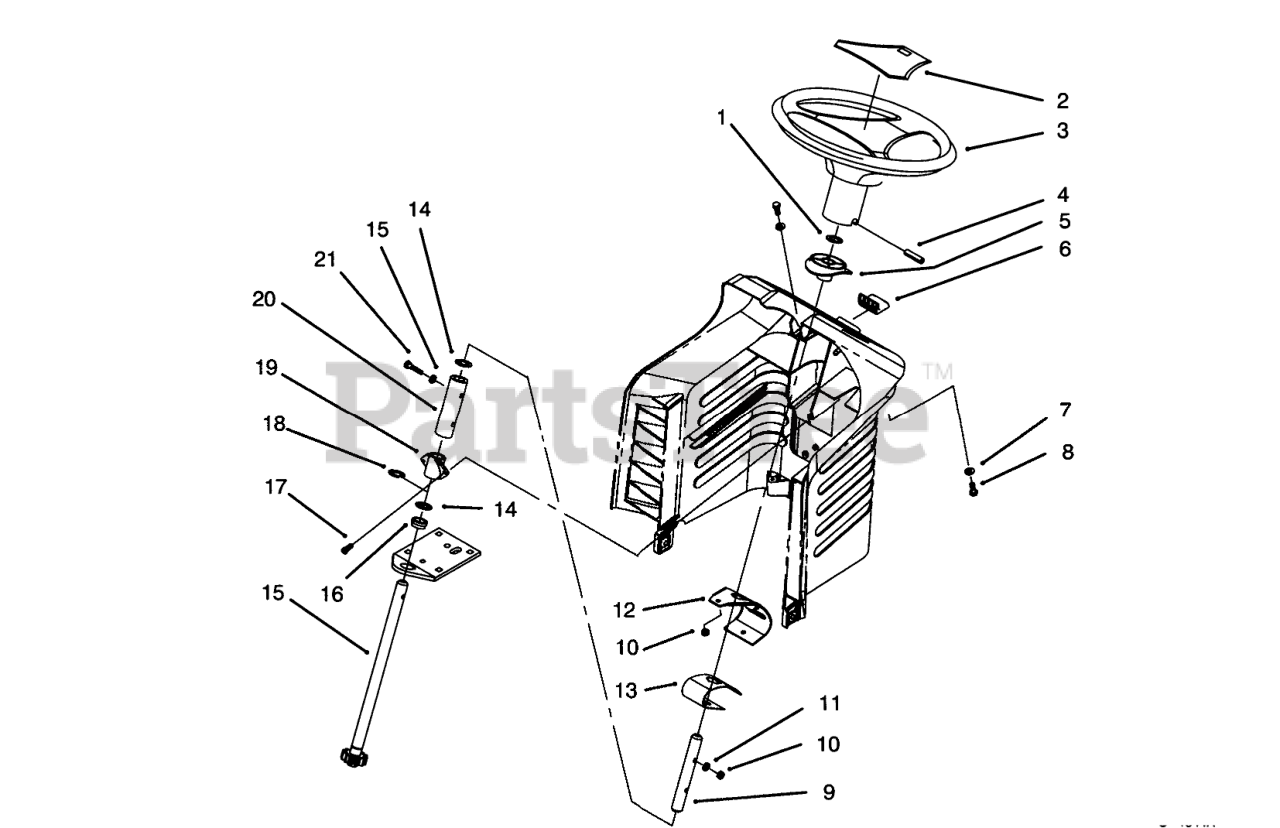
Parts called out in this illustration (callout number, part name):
1	PUSH-ON RETAINING RING
2	COVER-WHEEL
3	Wheel-Steering (Incl. Ref. #2)
4	PIN-ROLL
5	BUSHING-SLIDING
6	RELEASE BUTTON
7	WASHER-FLAT
8	SCREW-HH
9	UPPER STEERING SHAFT
10	NUT-LOCK, NI
11	WASHER
12	BACKUP BRACKET
13	SPRING LEAF
14	WASHER-THRUST
15	SHORT STRG SHAFT WA
16	BEARING-FLANGE
17	SCREW-SPECIAL
18	E-RING
19	BUSHING STATIONARY
20	COUPLING, STEERING
21	SCREW-HH
